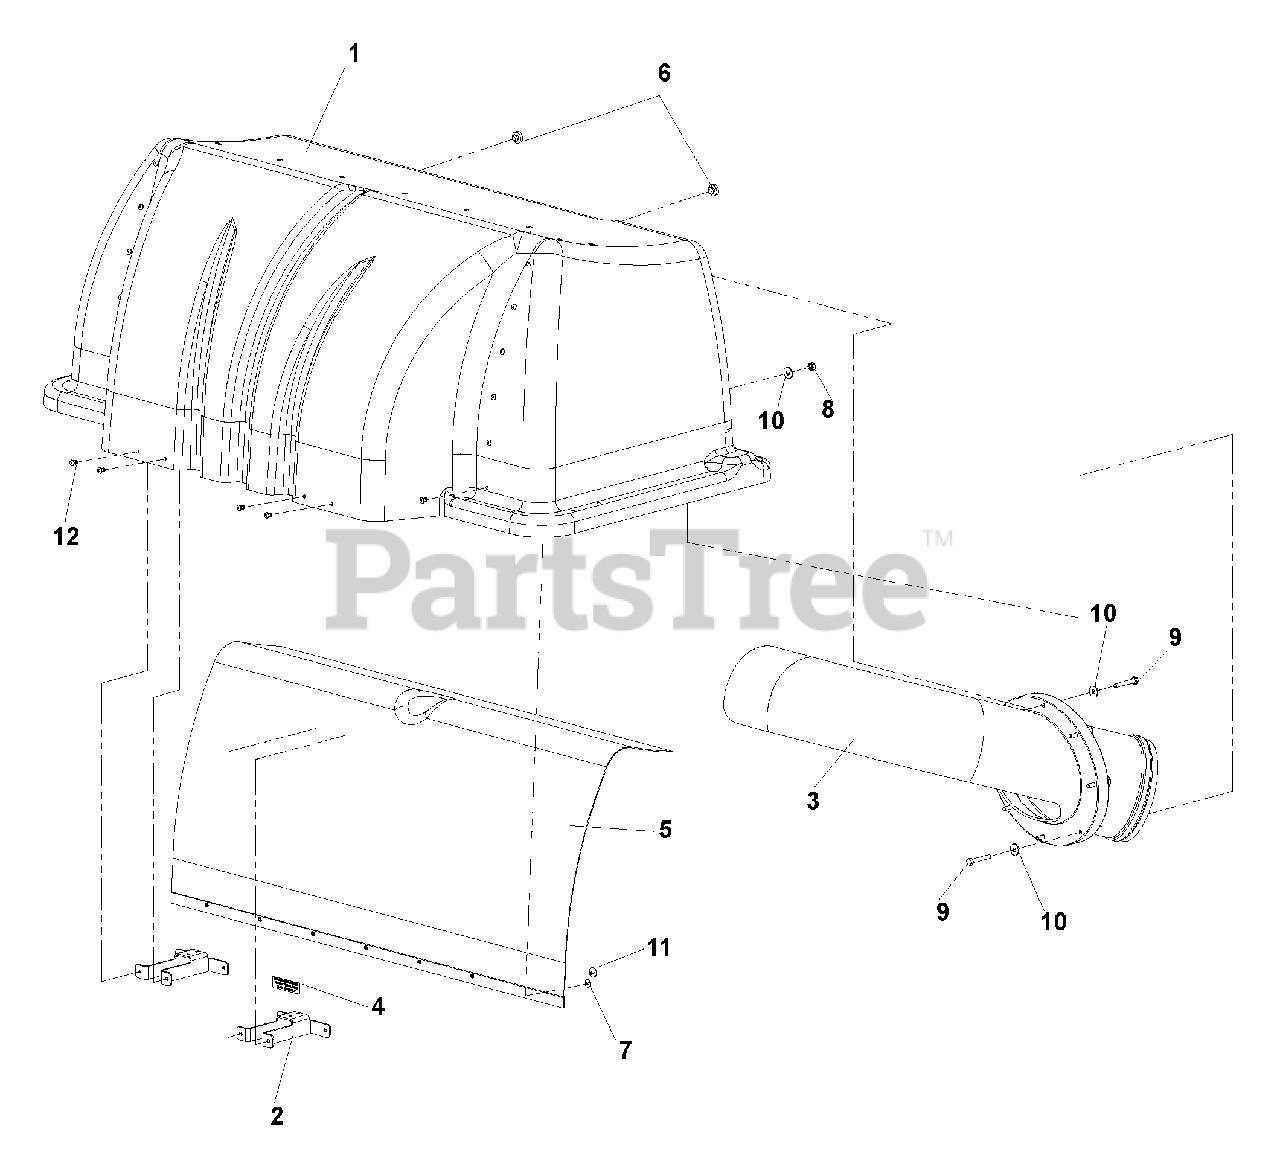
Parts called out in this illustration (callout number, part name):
2	SUPPORT, DRAW LATCH
3	INLET TUBE
4	DECAL, VENTILATION
5	MESH, POLY DIAMOND
6	GROMMET, BUMPER
7	WASHER, #10
8	NUT, 1/4-20, NYLOC
9	HCS, 1/4-20 X 1 3/4, GR5
10	WASHER, 1/4
11	RIVET, 3/16 X 1/4
12	RIVET, 3/16, STAVEX
